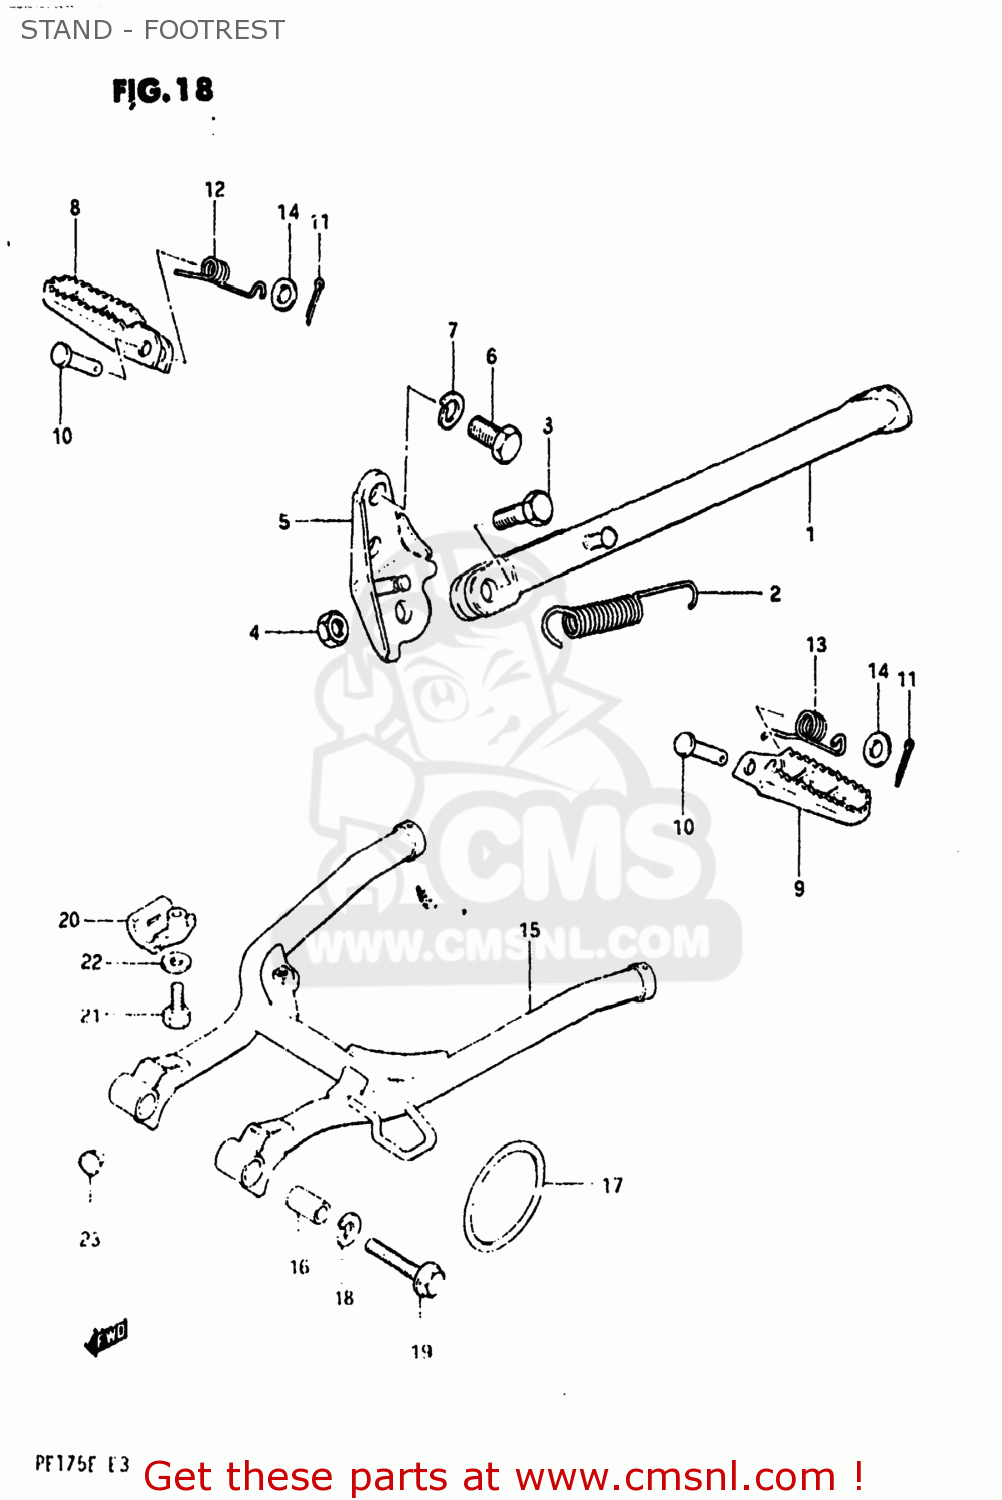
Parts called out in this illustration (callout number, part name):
1	STAND,SIDE
2	SPRING
3	BOLT(10X30)
4	NUT
5	BRACKET,SIDE STAND
6	BOLT(10X19)
7	LOCK WASHER
8	FOOTREST,RIGHT
9	FOOTREST
10	PIN
11	PIN 20X20
12	SPRING
13	SPRING
14	WASHER
15	STAND,CENTER
16	SPACER(10.5X16X30)
17	O RING CTR STAND
18	LOCK WASHER
19	BOLT
20	PROTECTOR CTR STAND
21	BOLT
22	WASHER
23	CUSHION
